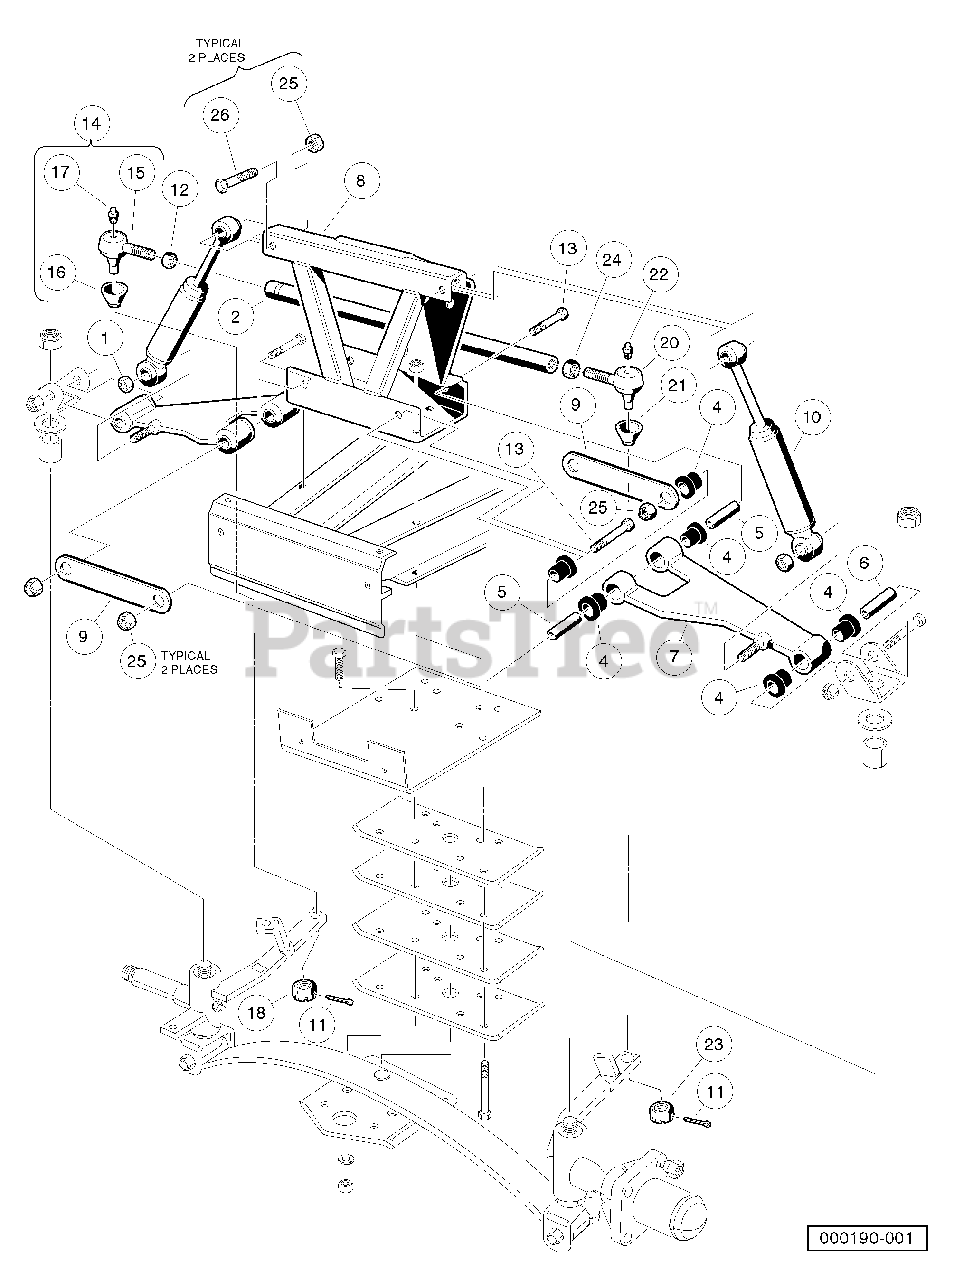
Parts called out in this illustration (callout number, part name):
1	Locknut, 3/8-16 Dimpled
3	Sub-Assembly, Delta A-Plate
4	Bushing, Urethane
5	Sleeve, Delta Inner
6	Sleeve, Delta Outer
7	DeIta A-Plate
8	Delta Shock and Gear Support Assembly
9	A-Plate Strap
10	Shock Absorber, Front, Common
11	Pin, 3/32 X 1.00 Sq Cut Cotter
12	Nut, 1/2-20 Hex
13	Screw, 3/8-16 X 2.25 Hx Hd Cap
14	Ball Joint, Right-Hand
15	Socket, RH Vertical
16	Seal, Vertical Socket Dust
17	Fitting, 1/4-28 Thread-Forming Grease
18	Nut, 3/8-24 UNF Hex
19	Ball Joint, Left
20	Socket, LH Vertical
21	Seal, Vertical Socket Dust
22	Fitting, 1/4-28 Thread-Forming Grease
23	Nut, 3/8-24 UNF Hex
24	Nut, 1/2-20 Hex, Left-Hand Thread
25	Locknut, 3/8-16 Hex
26	Bolt, 3/8-16 X 1.75 Hex
